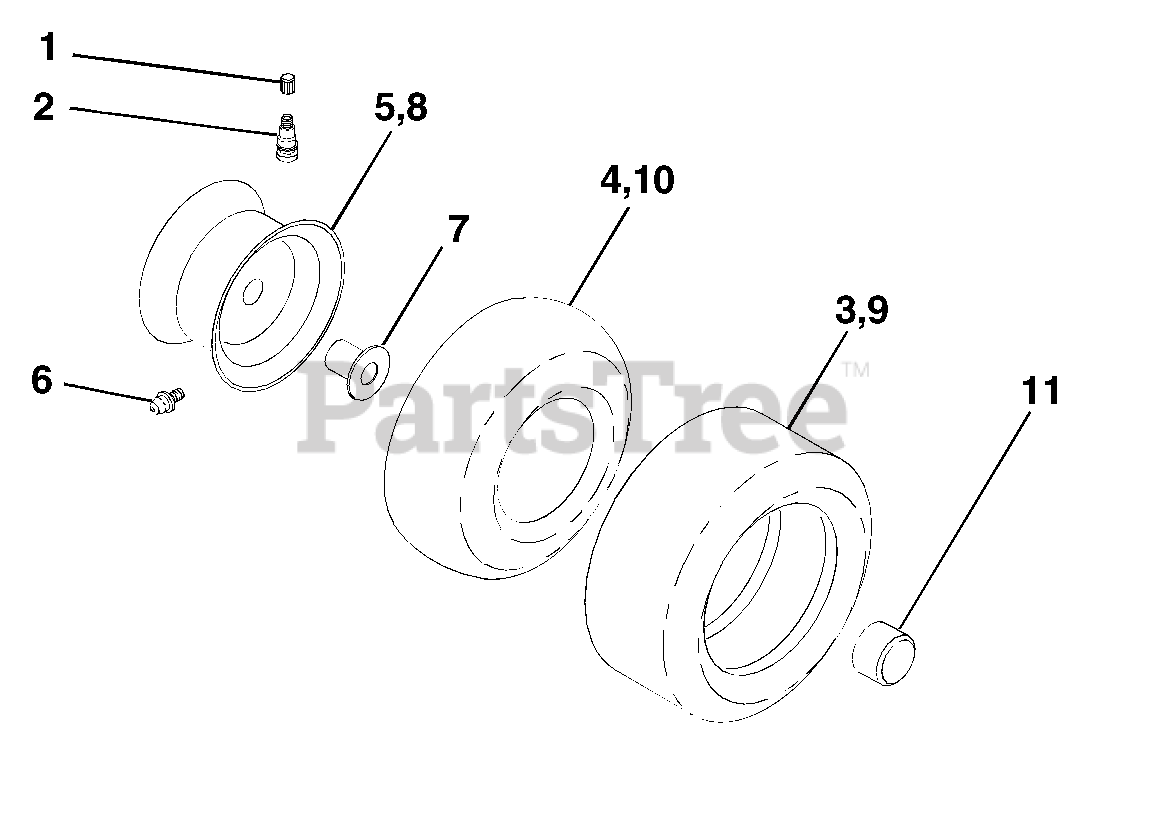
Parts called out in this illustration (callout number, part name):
1	Cap Valve Tire
2	Stem Valve
3	Tire F Ts 15 X 6 0 - 6 Service
4	Tube Front (Service Item Only)
5	Rim Asm 6"front Service
6	Fitting Grease (Front Wheel Only)
7	Bearing Flange (Front Wheel Only)
8	Rim Asm 8"rear Service
9	Tire R Ts 18x9.5-8 Service
10	Tube Rear (Service Item Only)
11	Cap Axle 1 50 X 1 00
